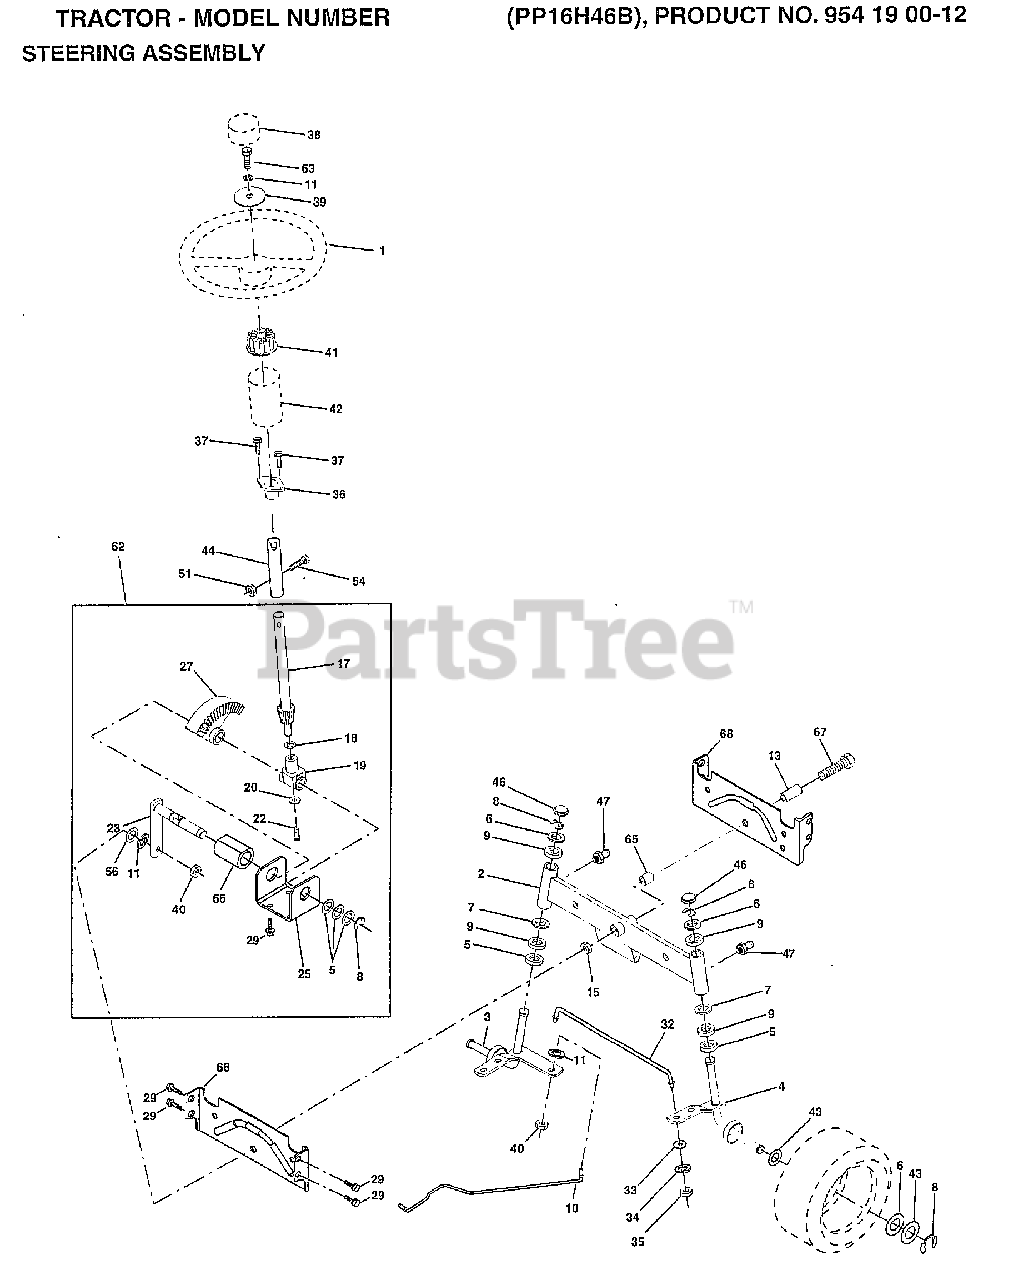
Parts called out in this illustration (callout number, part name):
2	AXLE ASM
3	SPINDLE.ASM.LH
4	"SPINDLE ASM,RH"
5	WASHER .T
6	WASHER
7	WASHER
8	RING
9	COL. SRTG. BEAR.
10	DRAGLINK-STAMPED
11	LOCKWASHER
13	BEARING AXLE
15	"NUT-LOC,FLANGE LT"
17	SHAFT ASM STEERIN
18	THRUST WASHER
19	SUPPORT SHAFT
20	WASHER SHIM 1/4 X 5/8 X 062
22	SCREW HEX SOC1/4-
25	BRKT-STEERING
27	GEAR SECTOR
29	SCREW
32	ROD.TIE.19.75
33	WASHER M
34	LOCKWASHER
35	NUT.LOCK.5/16-24
36	BUSHING.STEERING
37	"SCREW-TT,10-32 FL"
38	"INSERT,STR WHEEL"
39	WASHER T
40	GRIPCO NUT
41	ADAPTER LT
42	BOOT.STEER.PL
43	WASHER
44	EXT SHAFT STEERIN
46	CAP
47	ZERK M
51	NUT
54	BOLT
62	KIT STEERING ASM
63	BOLT
65	SPACER AXLE
66	"BEARING-ARM,PITMA"
67	BOLT
68	BRACE AXLE
